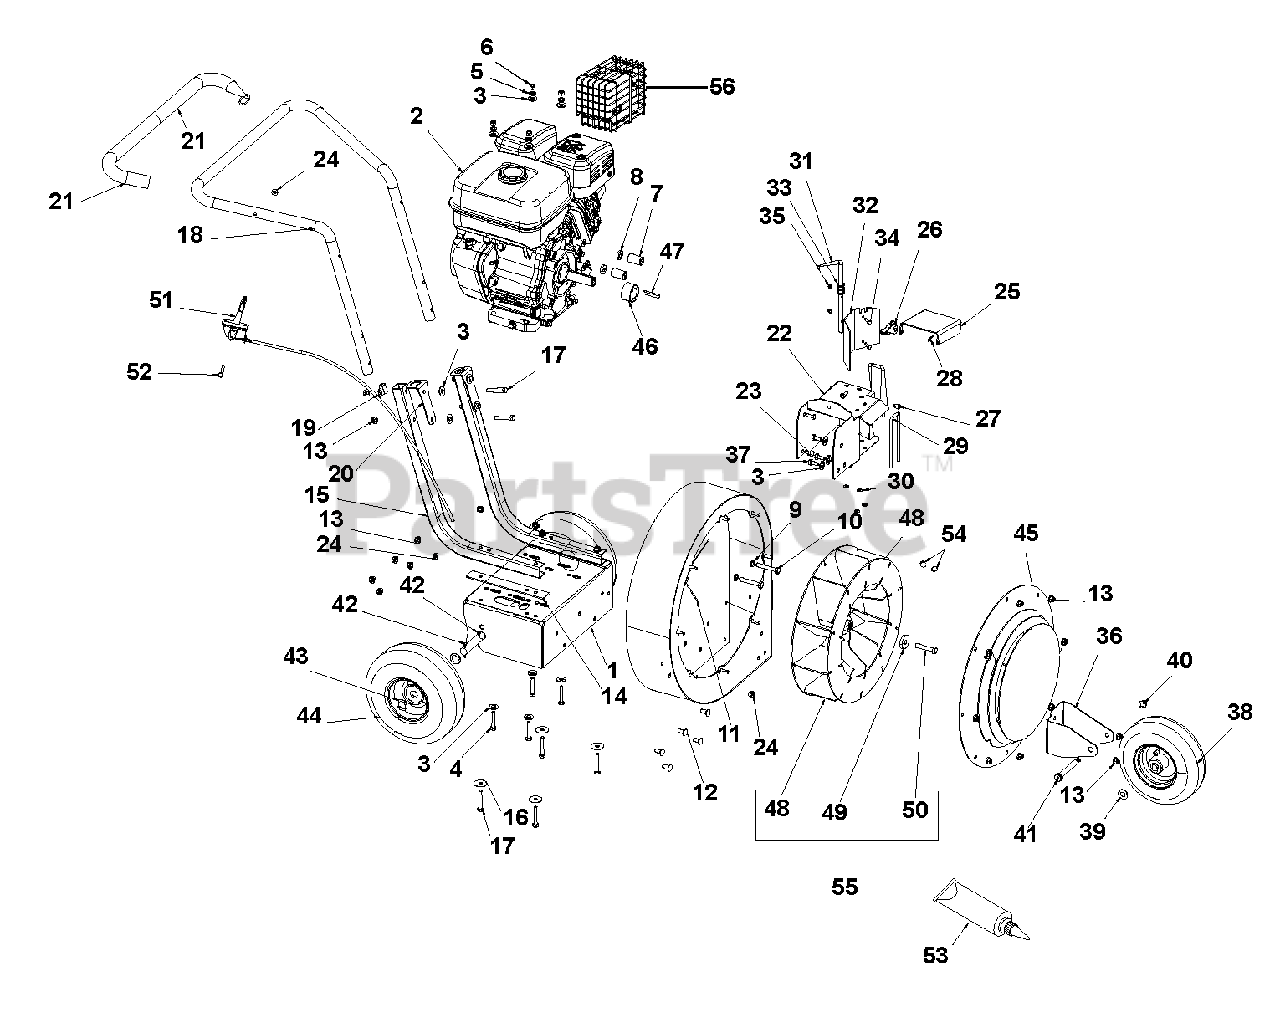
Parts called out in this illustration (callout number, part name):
1	Weldment, Blower Frame
2	Engine, SUBARU 9HP EX27 (CARB)
3	Washe, Flat Steel .38 x .875 x .083
4	Bolt, Hex .31-18 x 1.75 Grade 5
5	Washer, Locking .312 x .097 Heavy
6	Nut, Hex .31-18
7	Engine Spacer
8	Washer, Flat Steel .390 x .88 x .18
9	Washer, Locking .38 x .094 Regular
10	Bolt, Hex .38-16 x 2.25 Grade 5
11	Weldment, Blower Housing
12	Bolt, Round Head Square Neck .31-18 x .75 Grade 5
13	Nut, .31-18 Nyloc Flange
14	Rubber Spacer
15	Handlebar, Lower
16	Washer, Flat Steel .347 x 1.254 x .048
17	Bolt, Hex .31-18 x 2.00 Grade 5
18	Tube, Handlebar, Upper
20	Bracket, Handlebar Mount
21	Grip, Handlebar, Upper
22	Weldment, Outlet Chute
23	Bolt, Hex .25-20 x .75 Grade 5
24	Nut, .25-20 Nyloc Flange
25	Bracket, Outlet Door
26	Knob, Wing .31-18 UNC
27	Pin, Clevis .313 x .500
28	Pin, Hair
29	Wireform, Guard, Safety
30	Push, Nut 1/4
31	Wireform, Lever, Direction
32	Bracket, Flap, Direction
33	Spring, Compression 1.0L x .72 OD .05DIA
34	Screw, Machine 10-24 x .75 Hex Washer Head
35	Nut, Locking Nylon 10-24 with Insert
36	Bracket, Wheel, Front
37	Bolt, Hex .31-18 x .75 Grade 5 YWZC
38	Wheel, 9 x 2.5 PNEU-Grey Rim
39	Washer, Flat Nylon .52 x 1.00 x .08
40	Nut, Locking-Top-Flange .38-16
41	Bolt, Shoulder .5 x 3.25 x .38-16
42	Pin, Cotter .16 x 1.25 Extended Prong Square Cut
43	Washer, Flat Steel .754 x 1.125 x .062
44	Wheel, 10 x 3.75 Grey
45	Weldment, Inlet Guard Medium
46	Bushing, Sleeve, 1.0 x 2.0 x 1.0
47	Key, Square .25 x 1.75 x .25
48	Weldment, Fan, Impeller Medium
49	Washer, Flat Steel .463 x 1.375 x .250
50	Bolt, Hex .31-24 x 2.00 Grade 8
51	Throttle Control
52	Bolt, Hex .25-20 x 2.00 Grade 5
53	Loctite 609® .5 ml
54	Set Screw .331-18 x .38
55	Kit – 9hp Fan Replacement
56	Muffler Guard, Subaru EX27 (947301)
